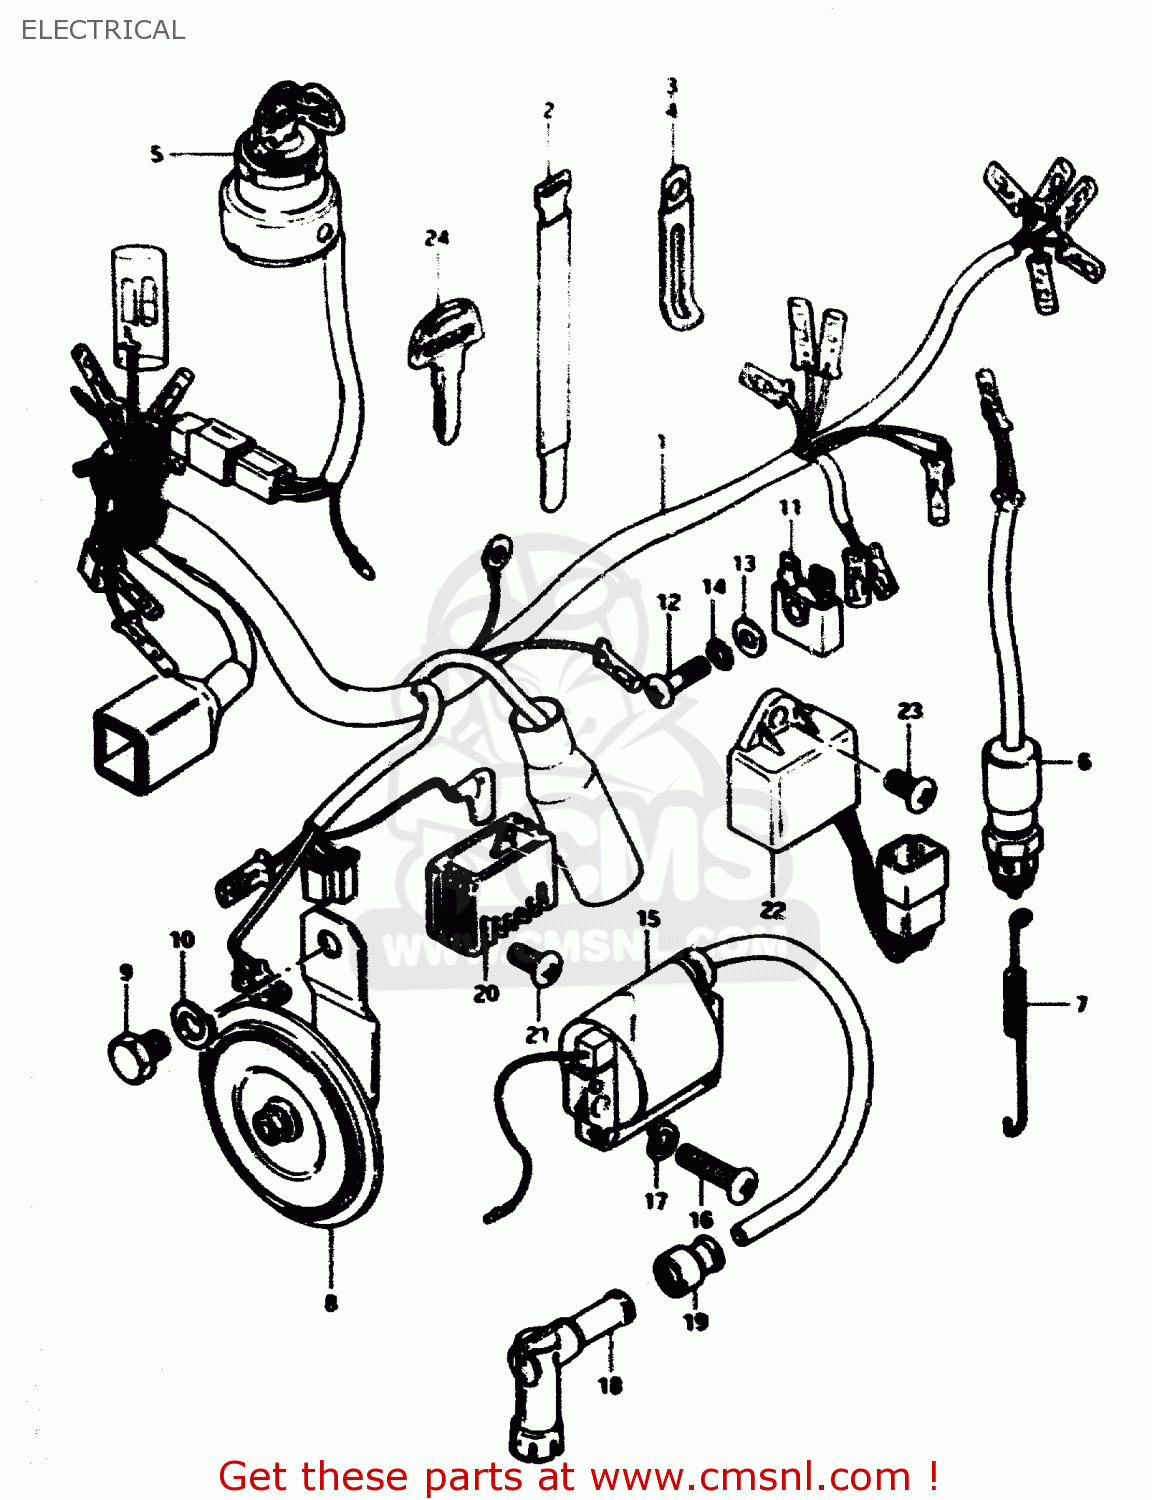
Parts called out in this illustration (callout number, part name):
1	WIRING HARNESS
2	CLAMP
3	CLAMP
4	CLAMP
5	SWITCH, IGNITION
6	SWITCH ASSEMBLY,STOP LAMP
7	SPRING
8	HORN
9	BOLT
10	WASHER
11	RECTIFIER ASSEMBLY
12	SCREW 5X20
13	WASHER
14	WASHER,LOCK
15	COIL, IGNITION
16	SCREW
17	LOCK WASHER
18	CAP,SPARK PLUG
19	SEAL,SPARK PLU
20	REGULATOR ASSY
21	SCREW 6X12
22	CDI UNIT
23	SCREW 6X12
24	KEY,BLANK
